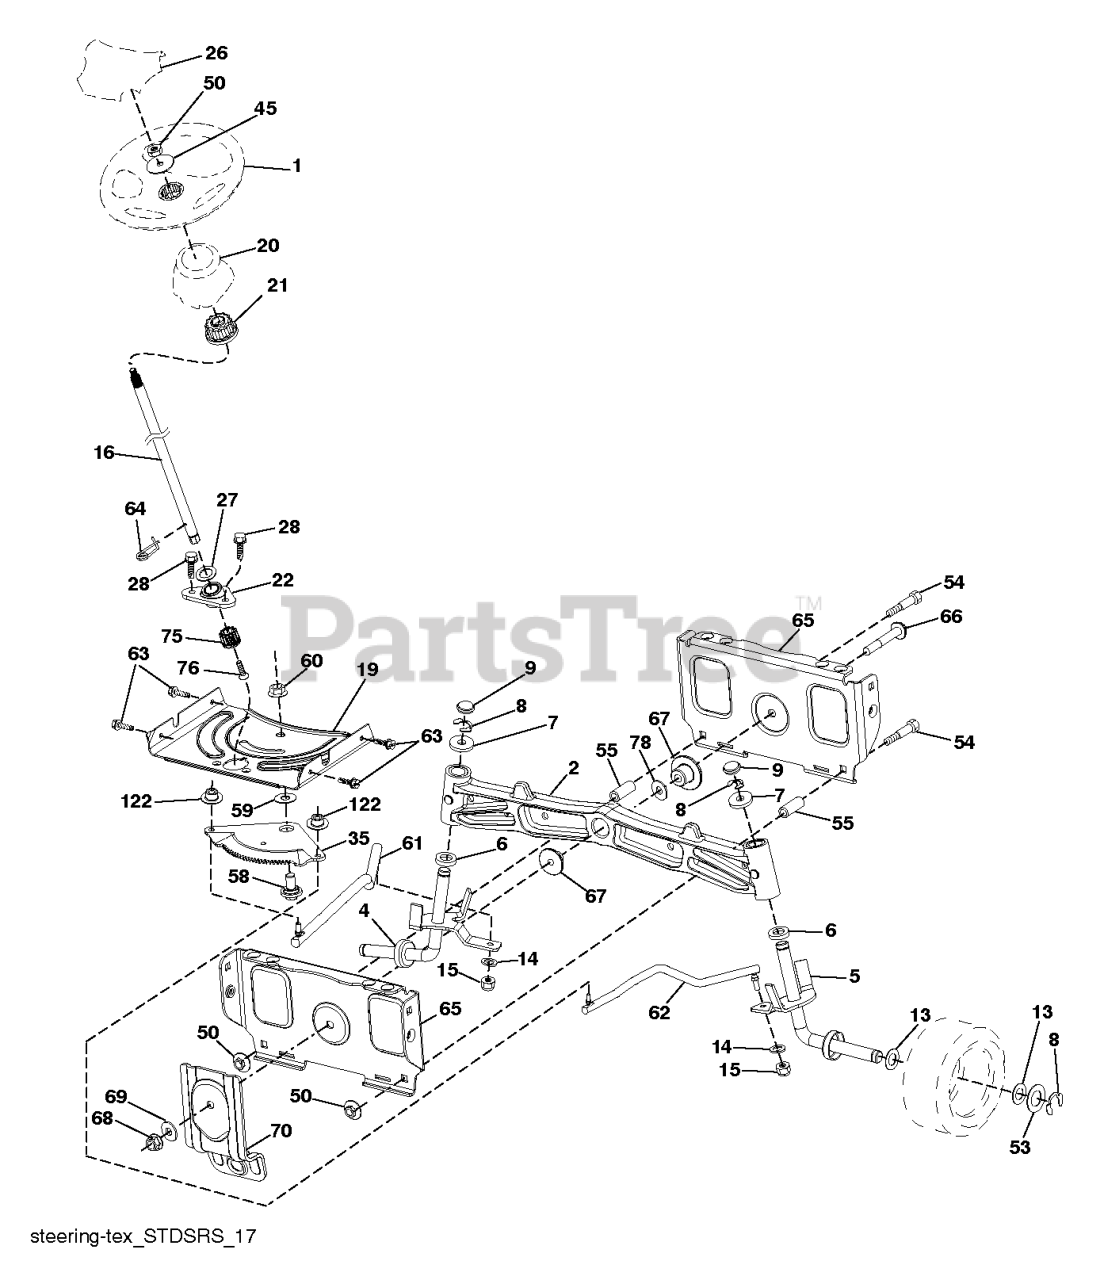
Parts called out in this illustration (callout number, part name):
1	WHEEL.STEERING.STDSRR.BLK/OV
2	AXLE.CAST.IRON
4	SPINDLE.ASM.LH
5	SPINDLE.ASM.RH
6	THRUST WASHER
8	RING CLIP
9	CAP.SPINDLE.BLACK
14	SLW 3/8 STD
15	NUT CROWNLOCK 3/8-24
16	SHAFT.STEER.2HIGH.SPLND.PLATED
19	PLATE.STEER.DDL.NLT/NG
20	BOOT.STRNG.PREDATOR.YT/GT.428
21	ADAPTER.WHEEL.STEER.SPLND.ALUM
22	BEARING.SHAFT.STEER.LOWER.625
26	INSERT, WHEEL STEERING
27	WASHER LT
28	SCREW, 3/8-16X3/4
35	GEAR.SECTOR.PLATE.DDL.
45	WASHER.3/8ID.2-3/8OD.12GA.PLTD
50	NUT LOCK FLG 3/8-16 UNC
53	WASHER.HARDENED
55	SPACER.BRACE.AXLE
58	BOLT.SHOULDER.SECTOR.P
59	WASHER.THURST.SECTOR.S
60	NUT FLANGE LOCK 5/8-11
61	LINK.ASM.DRAG.ADJUST.LH.PLATED
62	LINK.ASM.DRAG.ADJUST.RH.PLATED
63	SCREW
64	RETAINER.CLIP.SPRING.S
65	BRACE.AXLE.FRONT.NLT/N
66	BOLT HEX FGHD 7/16-14 X 3 SERR
67	BUSHING.PM.FRONT AXLE
68	NUT.LOCK.FLANGE.7/16
69	WASHER.1.5X.505X.118
70	BRACKET.FRT.DECK.SUSP.RR.MT431
75	PINION.ZINC PLATED
76	SCREW HEAD SOCKET LRVB
78	THRUST WASHER
122	CAP.GEAR.SECTOR.TEX
